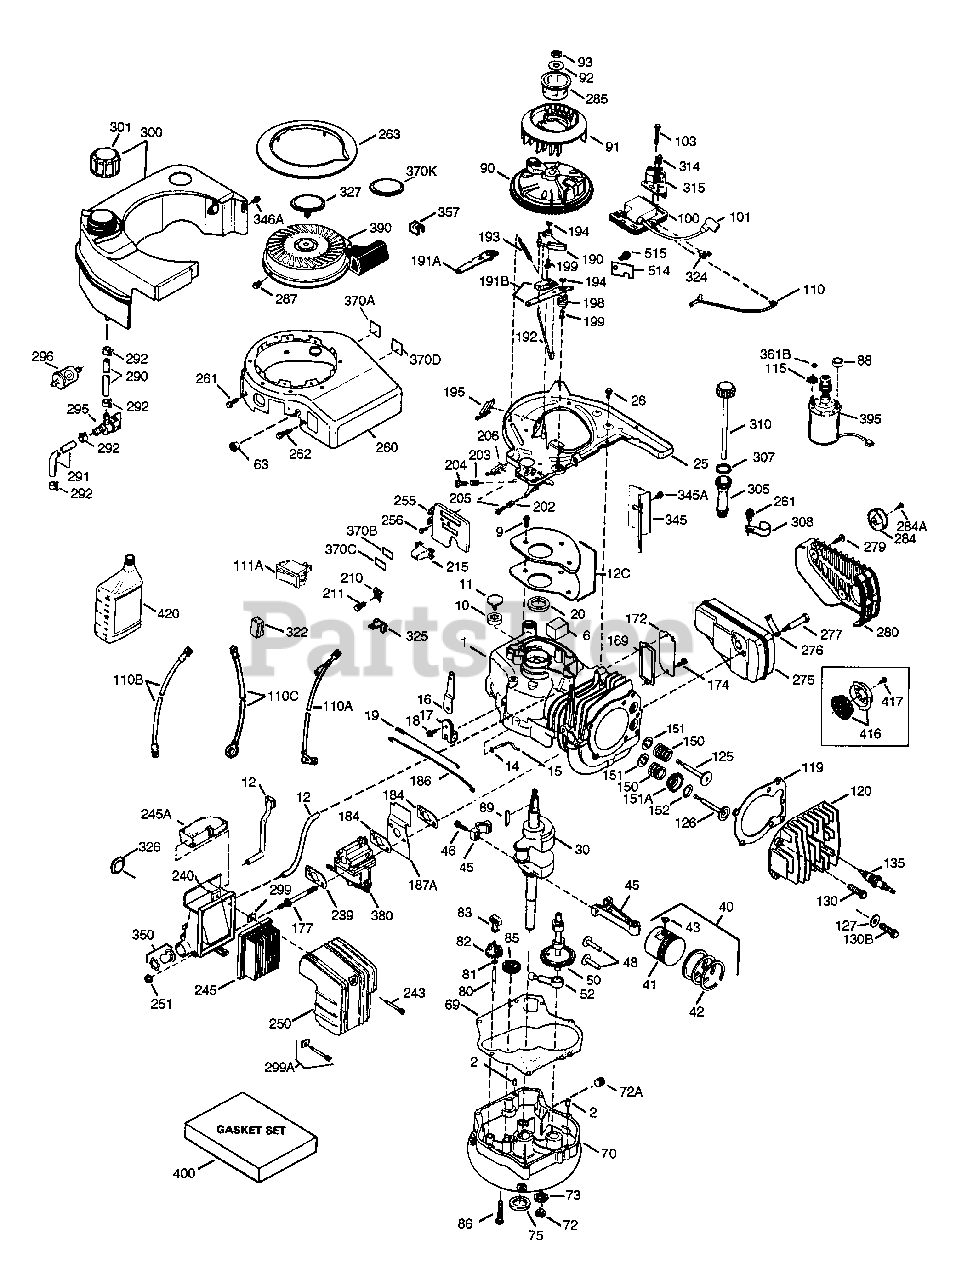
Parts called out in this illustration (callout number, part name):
1	"Cylinder (Incl. 2,10,12,20 & 125)
2	Dowel Pin
6	Breather Element
7	* Breather Cover & Gasket
9	Screw, 10-24 x 3/4"
10	Breather Valve Body
11	Check Valve
12	Breather Tube
14	Flat Washer
15	Governor Rod (Machined)
16	Governor Lever
17	Governor Lever Clamp
18	Screw, Torx T-15, 8-32 x 19/64"
19	Governor Spring
20	Oil Seal
25	Blower Housing Baffle Ass'y. Incl.l95
26	Screw, 1/4-20 x 5/8"
30	Crankshaft
40	Piston,Pin,Ring Set (Std.)
40	Piston,Pin,Ring Set (.010 OS)
40	Piston,Pin,Ring Set (.020 OS)
41	Piston & Pin Ass'y.(Std.) (Incl. 43)
41	Piston & Pin Ass'y.(.010 OS)(Incl.43)
41	Piston & Pin Ass'y.(.020 OS)(Incl.43)
42	Ring Set (Std.)
42	Ring Set (.010 OS)
42	Ring Set (.020 OS)
43	Piston Pin Retaining Ring
45	Connecting Rod Ass'y. (Incl. 46)
46	Connecting Rod Bolt
48	Valve Lifter
50	Camshaft (MCR)
52	Oil Pump Ass'y.
69	* Mounting Flange Gasket
70	Mounting Flange (Incl. 72 thru 85)
72	Oil Drain Plug (Incl. 73)
73	Drain Plug Gasket
75	Oil Seal
80	Governor Shaft
82	Governor Gear Ass'y. (Incl.81)
83	Governor Spool
85	Idler Gear
86	Screw, 1/4-20 x 1-9/16"
89	Flywheel Key
90	Flywheel
91	Flywheel Fan
92	Belleville Washer
93	Flywheel Nut
100	Solid State Ignition
101	Spark Plug Cover
103	Screw, Torx T-15, 10-24 x 15/16"
110	Ground Wire
119	* Cylinder Head Gasket
120	Cylinder Head
125	Exhaust Valve (Std.) (Incl. 151)
125	Exhaust Valve (1/32" OS)
126	Intake Valve (Std.) (Incl. 151)
126	Exhaust Valve (1/32" OS) (Incl. 151)
130	Screw, 5/16-18 x 1-1/2"
135	Resistor Spark Plug (RJ19LM) also ava ilable in Packaged Part #740081
150	Valve Spring
151	Lower Valve Spring Cap
151A	Intake Valve Seal
152	"O"-Ring
169	* Valve Spring Box Gasket
172	Valve Spring Box Cover
174	Screw, 10-24 x 9/16"
177	Carburetor Mounting Stud
184	Carburetor Gasket
186	Governor Link
187A	Air Baffle
190	Brake Lever Ass'y.
191A	Brake Control Lever
192	Brake Control Lever Link
193	Brake Spring
194	Retaining Ring
195	Terminal Ass'y.
198	Brake Control Lever Spring
199	Brake Lever Bushing
202	Compression Spring
203	Compression Spring
204	Screw, 5-40 x 7/16"
205	Screw, Torx T-10, 6-32 x 17/32"
215	Control Knob
239	* Carburetor To Air Cleaner Gasket
240	Air Cleaner Body (Incl.239 & 350)
245	Air Filter (Paper) (also available in Packaged Part #740031B for model VLV only) (also available in Packaged Pa rt #740061C for model OH195)
250	Air Cleaner Cover
251	Lock Nut 1/4-20
255	Control Plate
256	Screw, 8-32 x 21/64"
260	Blower Housing
261	Screw, 1/4-20 x 1/2"
262	Screw, 1/4-20 x 1/2"
275	Muffler
276	Locking Plate
277	Screw, 5/6-18 x 2-11/32"
285	Starter Cup
287	Screw, 8-32 x 21/64"
290	Fuel Line
292	Fuel Line Clamp
300	Fuel Tank (Incl. 301)
301	Fuel Cap
305	Oil Fill Tube
307	"O" Ring
308	Fill Tube Clip
310	Dipstick
346A	Screw, 10-32 x 35/64"
350	Primer
370A	Lubrication Decal
370B	Control Decal
370C	Primer Decal
380	Carburetor (Incl. 184,239)
390	Rewind Starter NOTE: This engine cou ld hav e been built with 590739 start er. Refer to the design of the rope p ulley strength ribs for part identifi cation. Individual starter parts do not interchange.
400	* Gasket Set (Incl. items marked PK in notes). Incl. part #'s 27234A (1), 2 8833 (1), 36005A (1), 36032A (1), 360 35 (1), 36048 (1), 36061 (1), 36183 ( 2), 696088 Instruction sheet ( 1)
416	Spark Arrestor Kit (Incl. 417) Option al
417	Screw, 8-32 x 3/8" (Optional)
900	Replacement Engine 750792B, order fro m 71-999
900	Replacement S/B 750797, order from 71 -999
999	Summer Maintenance Kit (incl. Oil, Sp ark Plug, Air Cleaner, & Ultra Fresh)
